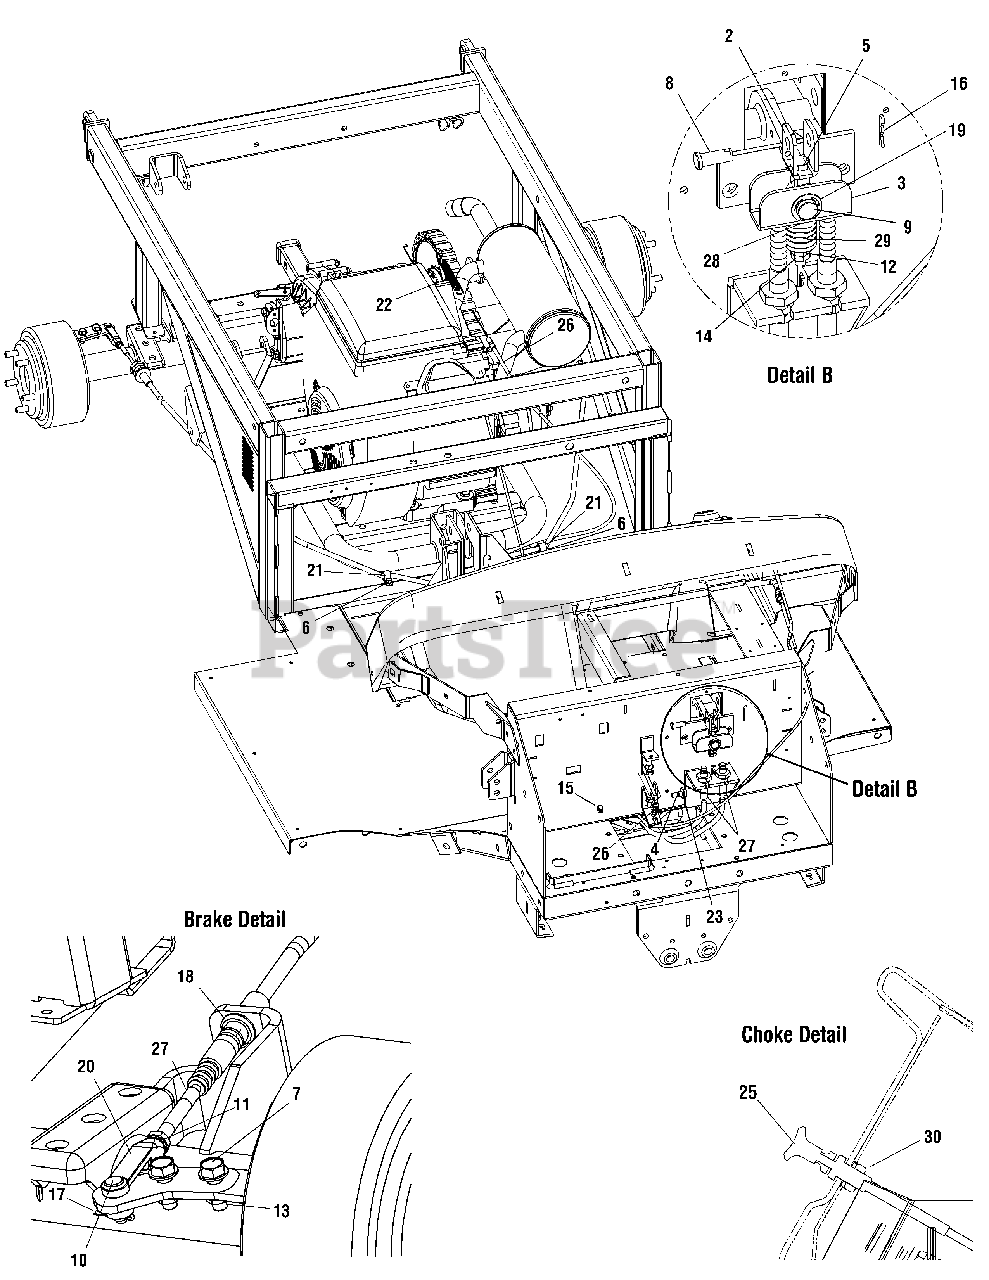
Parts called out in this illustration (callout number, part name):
1	Plate, Arm Brake
2	Mount,Cable
3	Bracket, Equalizer
4	Screw, Shoulder, .375 x .375
5	Screw, 5/16-18 x 3.5
6	Screw, Self-Tapping
7	Washer, 5/16-18 x .875
8	Pin, Clevis 375 x .969
9	Pin, Clevis .625 OD x 1.37
10	Pin, Clevis .312 OD x 1.0
11	Nut, Jam 5/16-24
12	Nut, Hex 5/16-18
13	Nut, FlangeLock 5/16-18
14	Nut, Jam 5/16-18
15	Hexlock Nut, 5/16-18
16	Pin, Cotter, .072 x 1.13
17	Pin, Cotter 3-32 x .750
18	E-Ring for .500 Dia Shaft
19	E-Ring.625 Shaft
20	Yoke, 5/16-24
22	Extension Spring
23	Washer, .349 x .879 x .063
24	Flat Washer, 1.0 x .56 x .040
25	Cable, Control, Choke
26	Cable, Control, Throttle
27	Cable, Control, Brake
28	Spacer, .466 OD x .443
29	Washer, Belleville, .937 x .328 x .07
30	Jam Lock Nut
